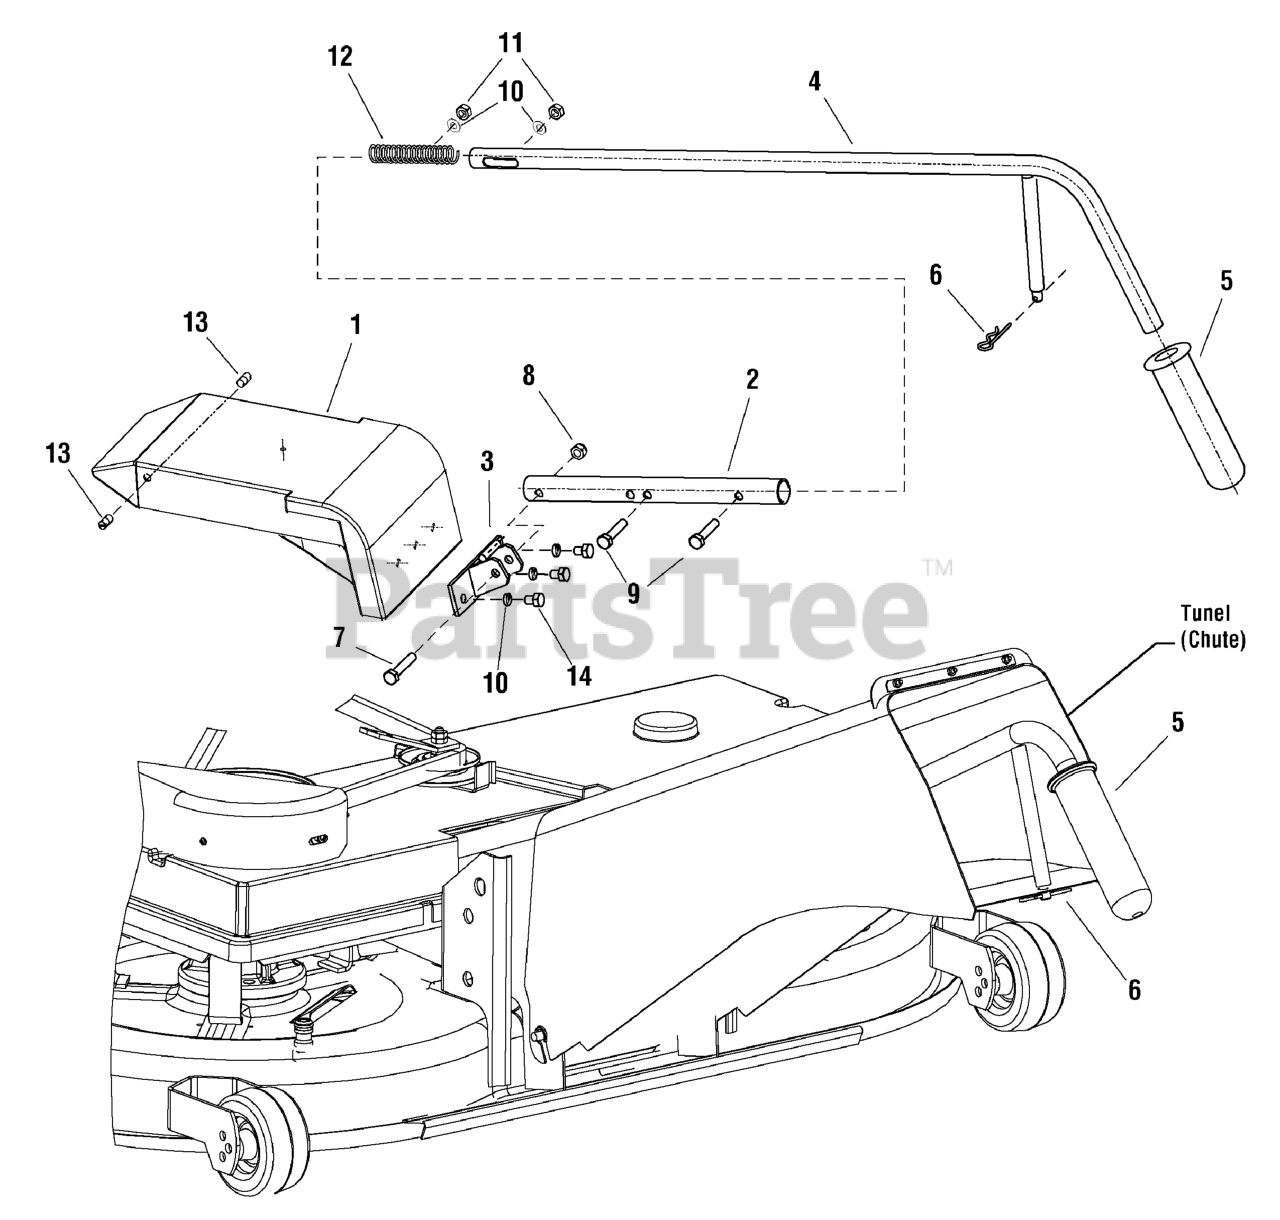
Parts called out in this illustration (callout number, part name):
1	FLANGE, Mowing
4	FULL TUBE
6	SPLIT PIN
7	SCREW, M8 x 45
8	NUT, M8
9	SCREW, M8 x 35
10	WASHER, 8
11	NUT, M8
14	SCREW, M8 x 12
